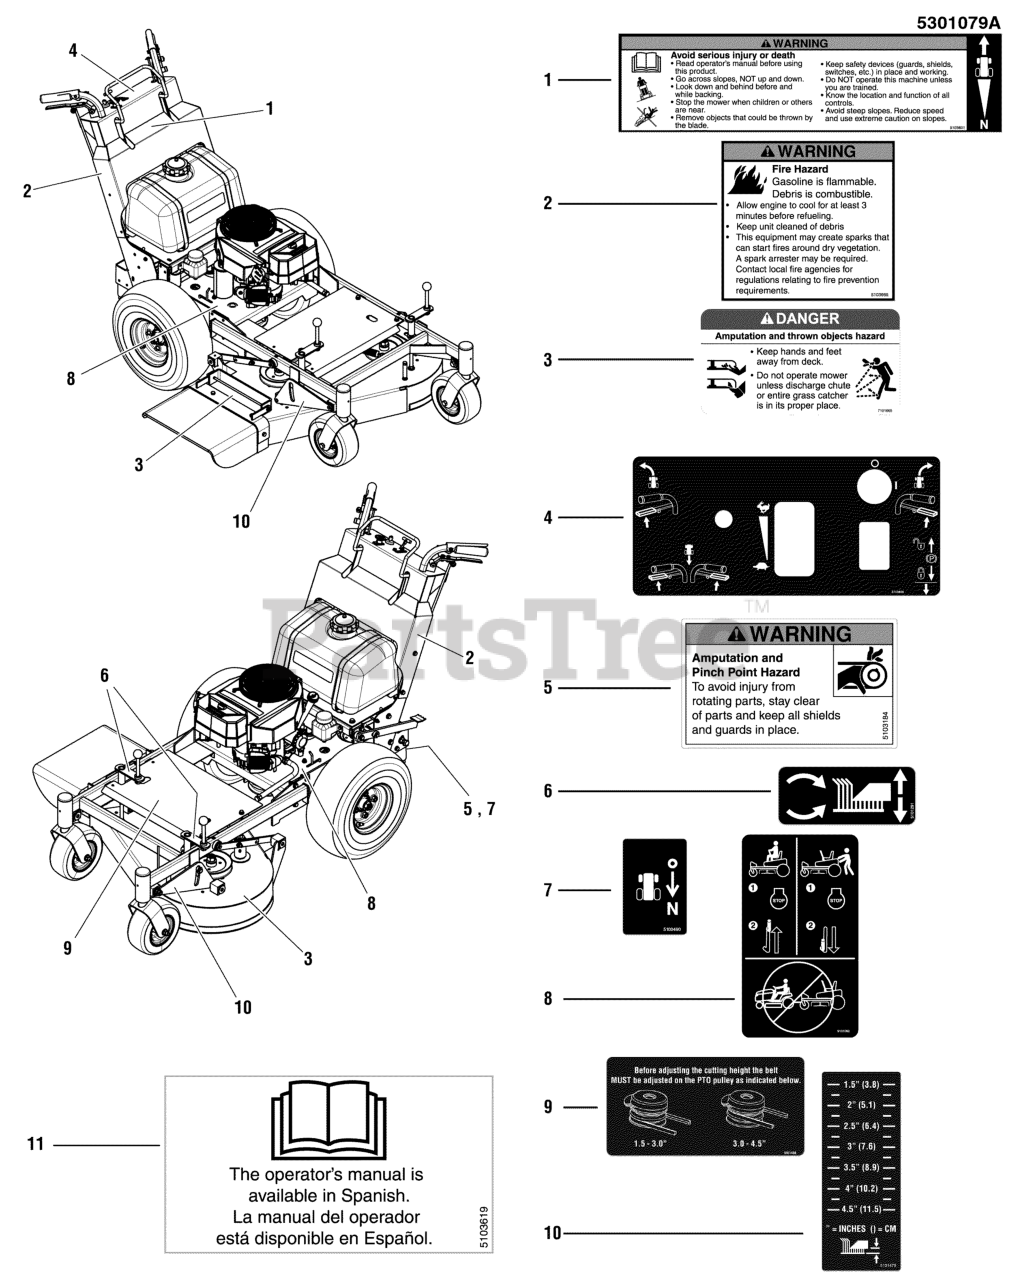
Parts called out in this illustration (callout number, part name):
1	DECAL, WARNING, WALKS
2	DECAL, FIRE HARARD, 3.25W X 3.0H
3	DECAL, DANGER DO NOT OPERATE W/O DEFLECT
4	DECAL, CONROL PANEL, WB
5	DECAL, WARNING, HAND IN BELT, ENG ONLY
6	DECAL, CUT HEIGHT, SPDD
7	DECAL, PEDAL
8	DECAL, TRANSAXLE RELEASE
9	DECAL, BELT LOCATION, PTO, SW20
10	DECAL, CUT HEIGHT, SW-20
11	DECAL, MANUAL AVAIL IN SPANISH
